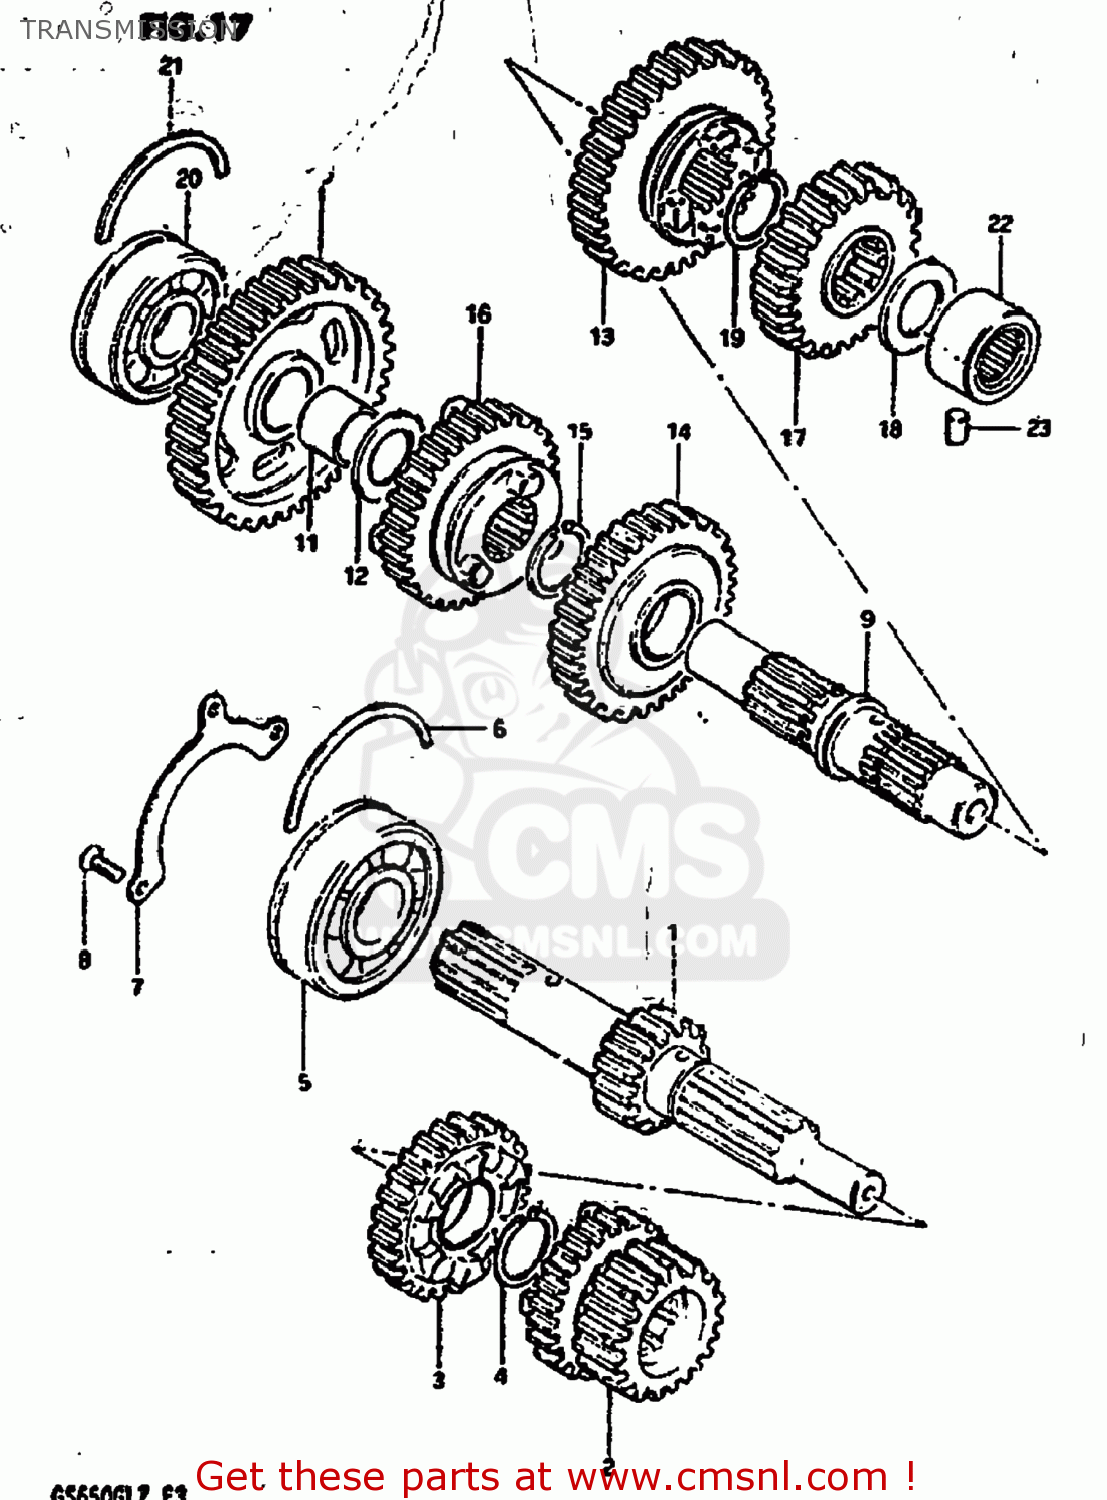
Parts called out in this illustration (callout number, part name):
1	SHAFT,COUNTER
2	GEAR,SECOND DRIVE
3	GEAR,FOURTH DRIVE
4	CIRCLIP
5	BEARING(25X62X17)
6	C-RING
7	RETAINER,CNTR SHAFT BEARING
8	SCREW
9	SHAFT,DRIVE
10	GEAR,FIRST DRIVEN
11	BUSHING
12	WASHER,THRUST
13	GEAR,SECOND DRIVEN
14	GEAR,THIRD DRIVEN
15	CIRCLIP
16	GEAR,FOURTH DRIVEN
17	GEAR,REDUCTION(NT:24)
18	THRUST WASHER,REDUCTION
19	CIRCLIP
20	BALL BEARING 20X47X14
21	C RING
22	BEARING(20X34X16)
23	PIN
